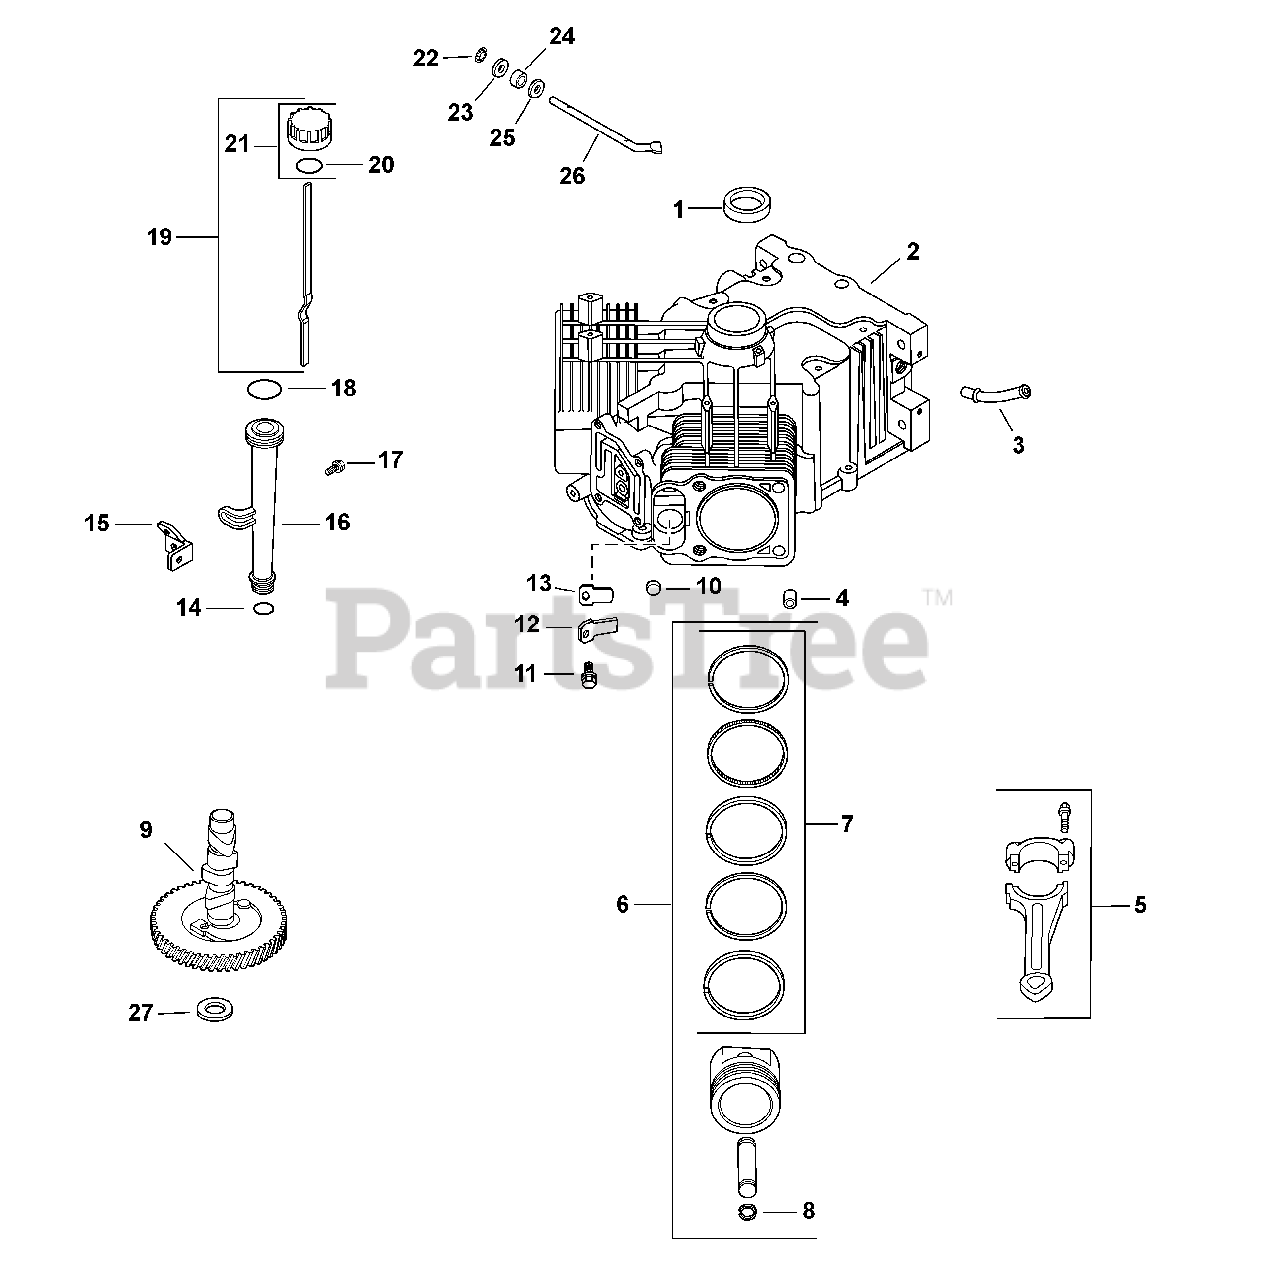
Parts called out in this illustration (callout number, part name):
2	Crankcase
4	Pin, Locating
5	Connecting Rod (STD)
5	Connecting Rod (.25)
6	Kit, Piston w/ Ring (STD) (Includes 7, 8)
6	Kit, Piston w/ Ring (.08)
6	Kit, Piston w/ Ring (.25)
6	Kit, Piston w/ Ring (.50)
7	Ring Set, Piston (STD)
7	Ring Set, Piston (.08)
7	Ring Set, Piston (.25)
7	Ring Set, Piston (.50)
8	Retainer, Piston Pin
9	Kit, Camshaft
11	Screw, Flg Thd Frm M5x0.8x10
12	Retainer, Breather Reed
13	Reed, Breather
14	O-Ring, Lower Oil Fill Tube
15	Bracket, Oil Fill Tube
16	Tube, Oil Fill Assembly
17	Screw, Flg Thd Frm M5x0.8x16
18	O-Ring, Upper Oil Fill Tube
19	Dipstick, Assy (Includes 20, 21)
20	O-Ring, Dipstick
21	Kit, Oil Fill Cap (Yellow)
22	Retainer, Ring
23	Washer, Flat 9MM
24	Seal, Governor Cross Shaft
25	Washer, Flat 1/4" (Bottom)
26	Shaft, Governor Cross
27	Camshaft Shim (White .028")
